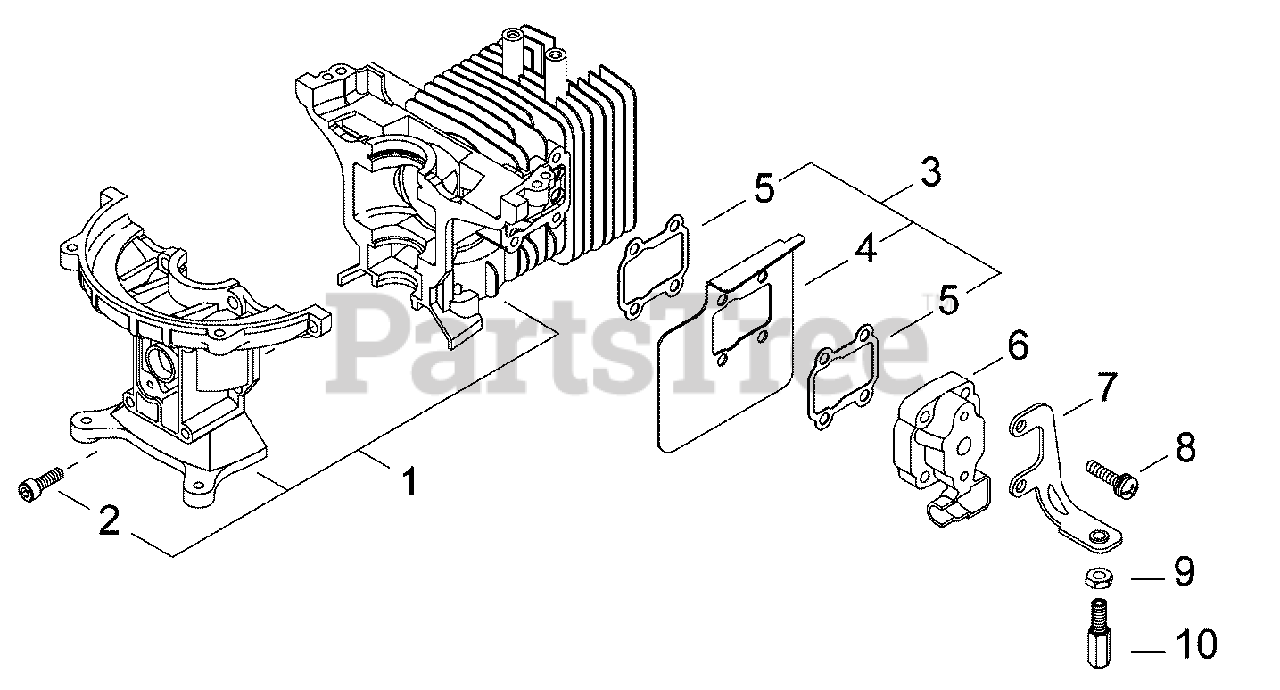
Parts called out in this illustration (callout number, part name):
1	CYLINDER & CRANKCASE ASSY
2	BOLT 5×16
3	SHIELD ASSY, INTAKE HEAT
4	HEAT SHIELD, INTAKE
5	GASKET, EXHAUST
6	INSULATOR WITH REED VALVE
7	BRACKET, THROTTLE CABLE
8	SCREW M5×22
9	NUT, ADJUSTER LOCK M6
10	ADJUSTER, THROTTLE CABLE
